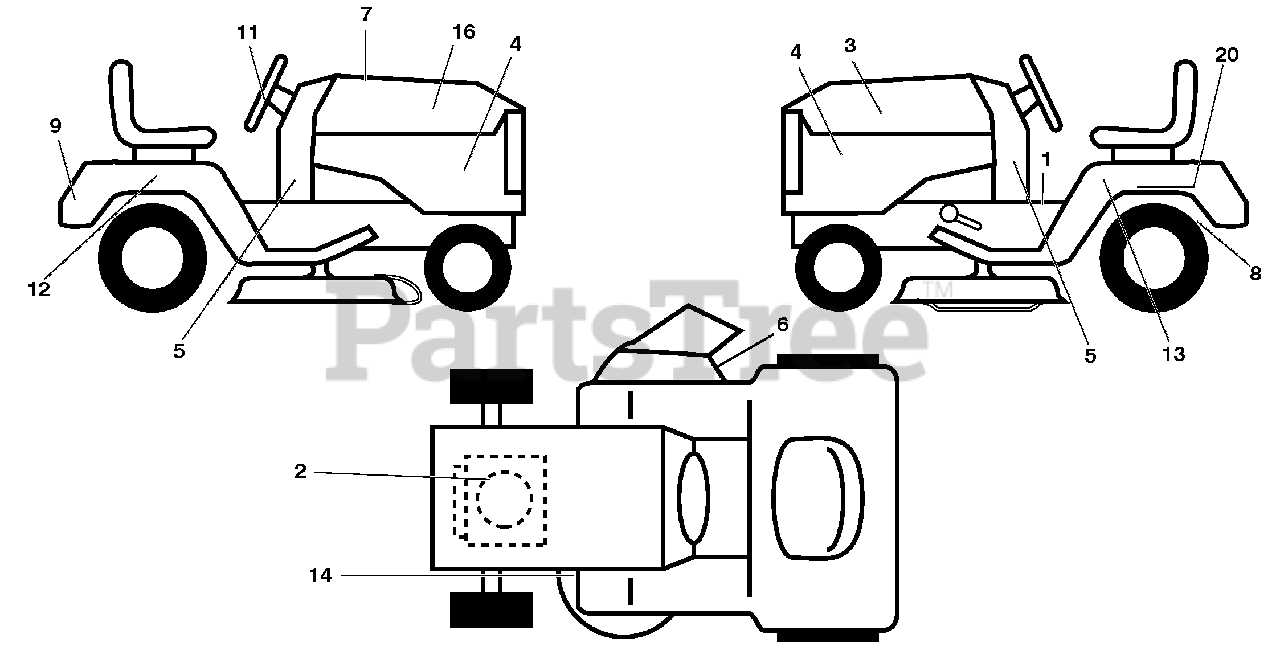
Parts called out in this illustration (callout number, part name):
1	Decal Fend. INS/WRN.HYDO
2	Decal Engine H.P.
3	Decal Hood LH
4	Decal Side Panel
5	Decal Lwr Dash
6	Decal Warning, Keep Hand Away
7	Decal Replacement Parts
8	Decal Bypass
9	Decal Fender Logo
11	Decal Ins Strg Whl
12	Decal Fender SD RH
13	Decal Fender SD LH
14	Decal V-Belt Schematic
16	Decal Hood Rh
20	Decal Bat Dan/Psn
20	Pad Footrest LH
20	Pad Footrest RH
20	Manual Operator's E&F
20	Manual Parts
